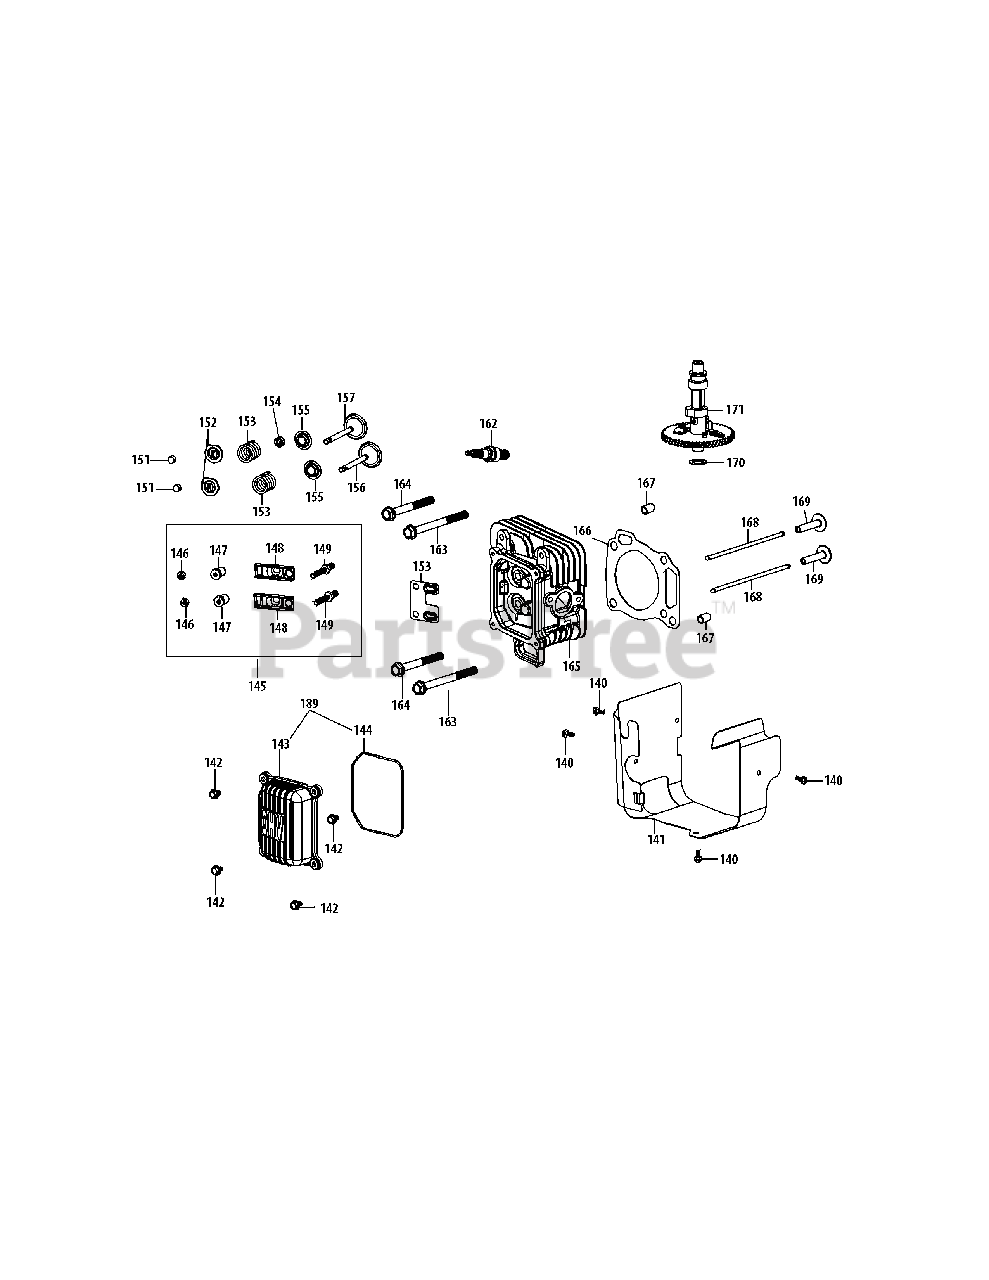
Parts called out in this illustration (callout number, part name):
140	Bolt M5×10
141	Cowl Shield
142	Valve Cover Bolt M 6 X 22
143	Valve Cover
144	Valve Cover Ring Gasket
145	Rocker Arm Assembly
146	Jam Pivot Locking Nut
147	Fulcrum Valve Adjusting Nut
148	Rocker Arm
149	Rocker Arm Stud
150	Push Rod Guide
151	Exhaust Valve Adjuster
152	Exhaust Valve Spring Retainer
153	Valve Spring
154	Intake Valve Seal
155	Valve Spring Retainer
156	Exhaust Valve
157	Intake Valve
161	Muffler Stud Assembly
162	Spark Plug
163	Bolt M10×1.25×85
164	Bolt /M10×1.25×65
165	Cylinder Head Asm
166	Cylinder Head Gasket
167	Cylinder Head Dowel Pin 12×16
168	Push Rod
169	Tappet
170	Camshaft Thrust Washer
171	Camshaft Assembly
189	Valve Cover Kit
